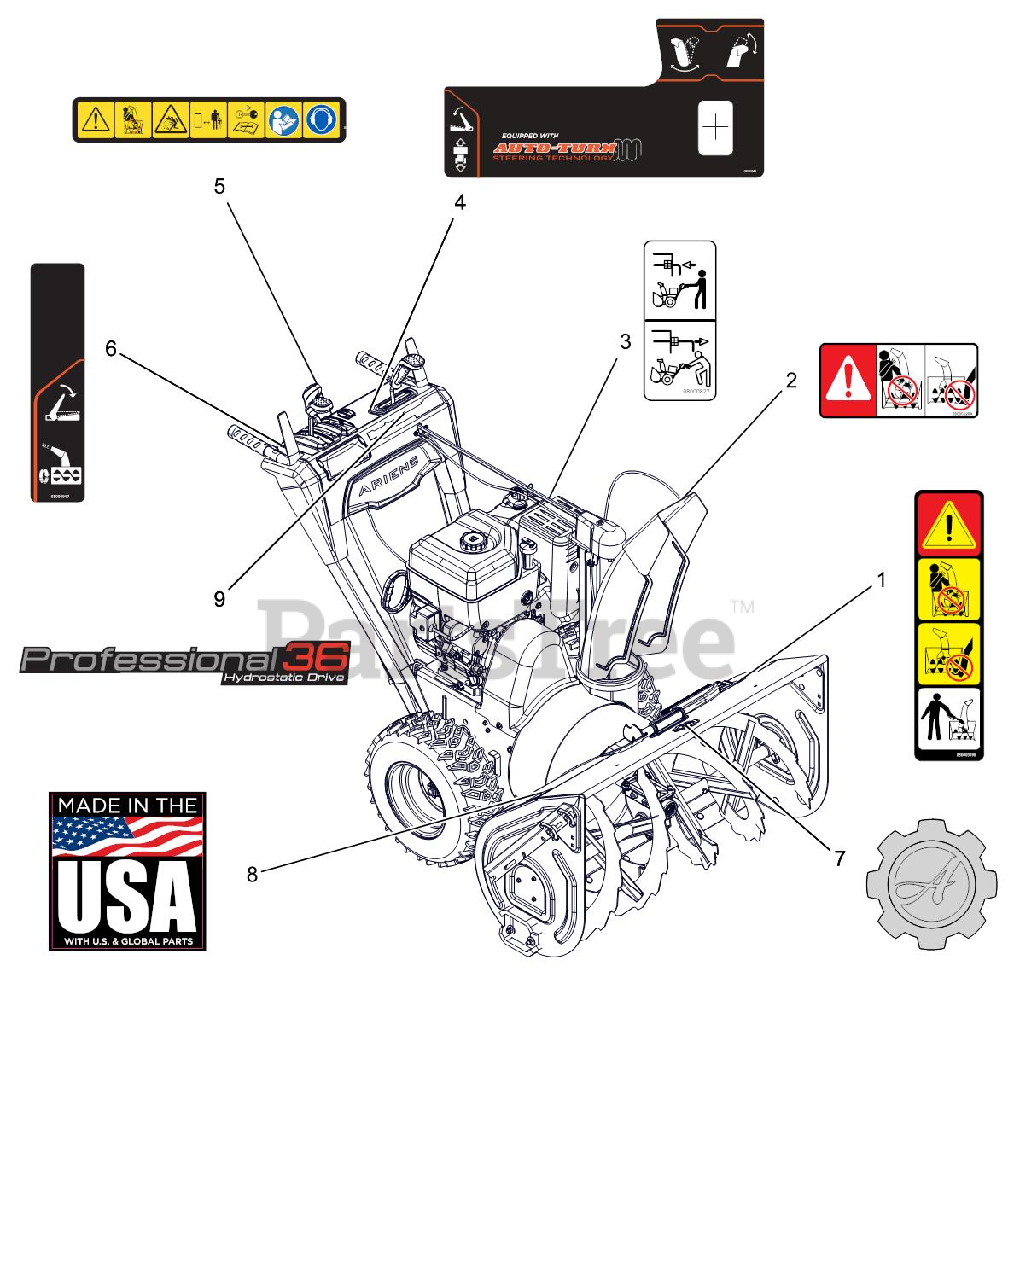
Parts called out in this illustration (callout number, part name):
1	DECAL, DANGER - ROTATING PARTS
2	DECAL, DANGER
3	DECAL, BYPASS
4	DECAL,CONTROL-LG QT2
5	DECAL,DASH - SAFETY
6	DECAL,CONTROL-RH CONTROL
7	DECAL, ARIENS-GEAR BADGE
8	DECAL, MADE IN USA
9	DECAL, DASH - PRO HYDRO 36
